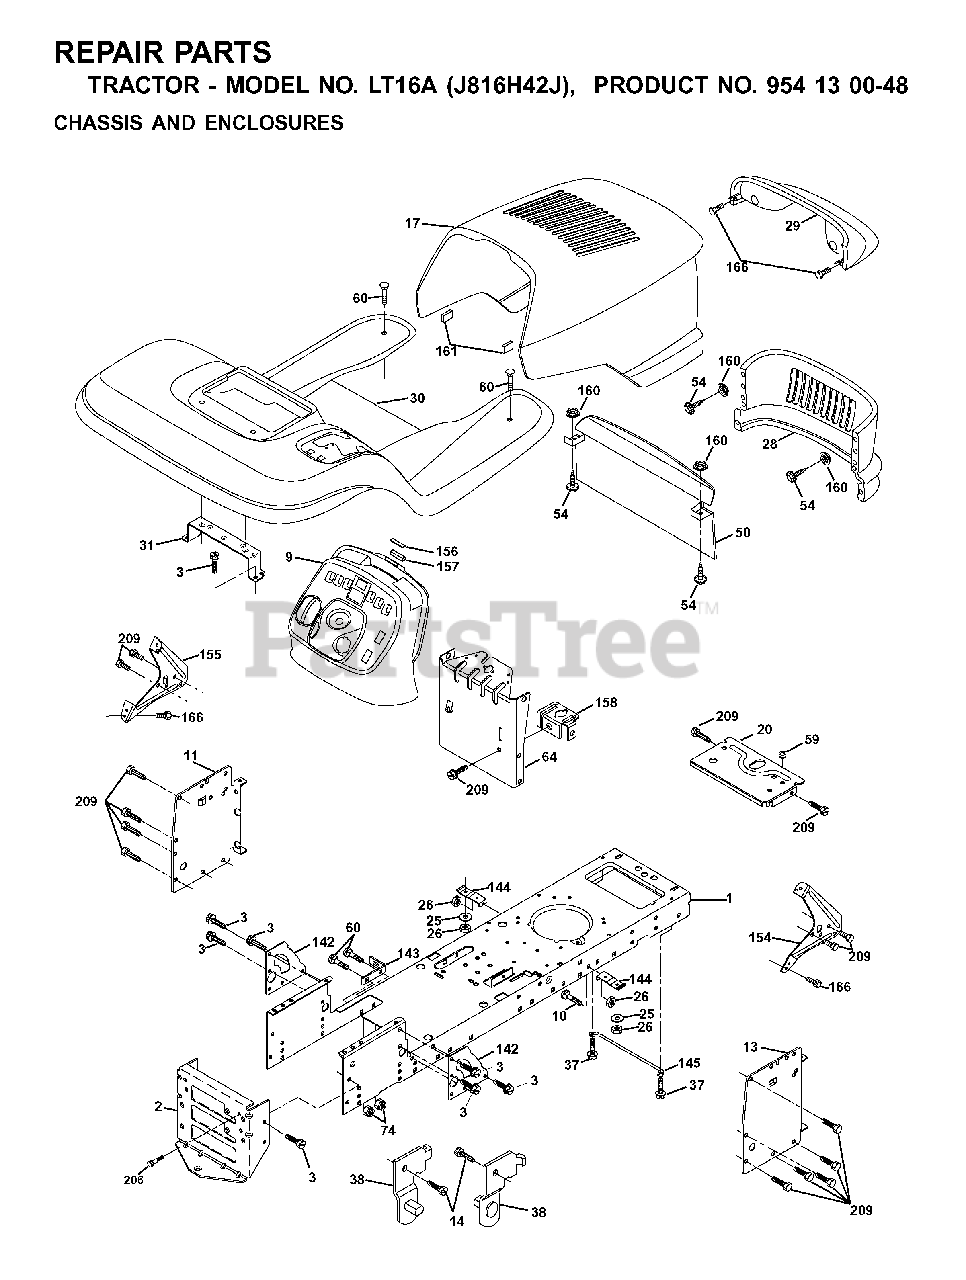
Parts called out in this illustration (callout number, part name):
1	CHASSIS STAMPING
2	DRAWBAR, 12GA
3	SCREW 3/8-16X3/4
10	BOLT D
25	WASHER
26	NUT
38	BRACKET
59	SNAP BUSHING T
74	LOCKNUT
142	PLATE
143	BRACKET, SWAY BAR
144	BRACKET FOOTREST
145	ROD PIVOT CHASSIS/HOOD
161	EXTRUSION BUMPER
166	SCREW
206	SHOULDER BOLT 5/16-18TT
209	SCREW, 3/8-16X3/4
